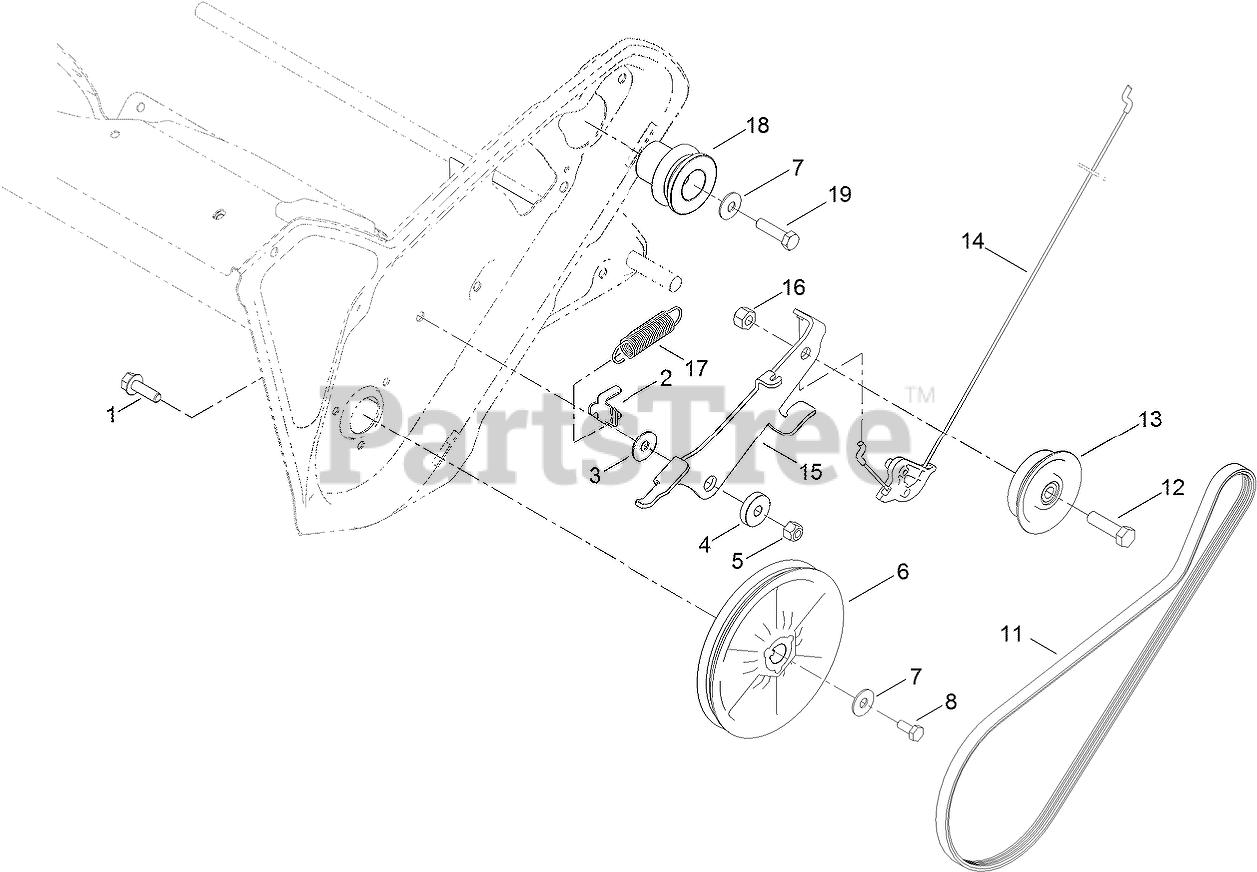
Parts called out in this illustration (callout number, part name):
1	SCREW-HHF
2	CLIP-SPRING, BRAKE
3	WASHER
4	BUSHING-PIVOT
5	NUT-LOCK, NI
6	PULLEY
7	WASHER-BELLEVILLE
8	SCREW-HH
11	BELT-DRIVE
12	SCREW-HH
13	PULLEY-IDLER
14	CABLE-CLUTCH
15	ARM-IDLER
16	NUT-LOCK, CONE
17	SPRING-EXTENSION
18	PULLEY-ENGINE
19	SCREW-HH
